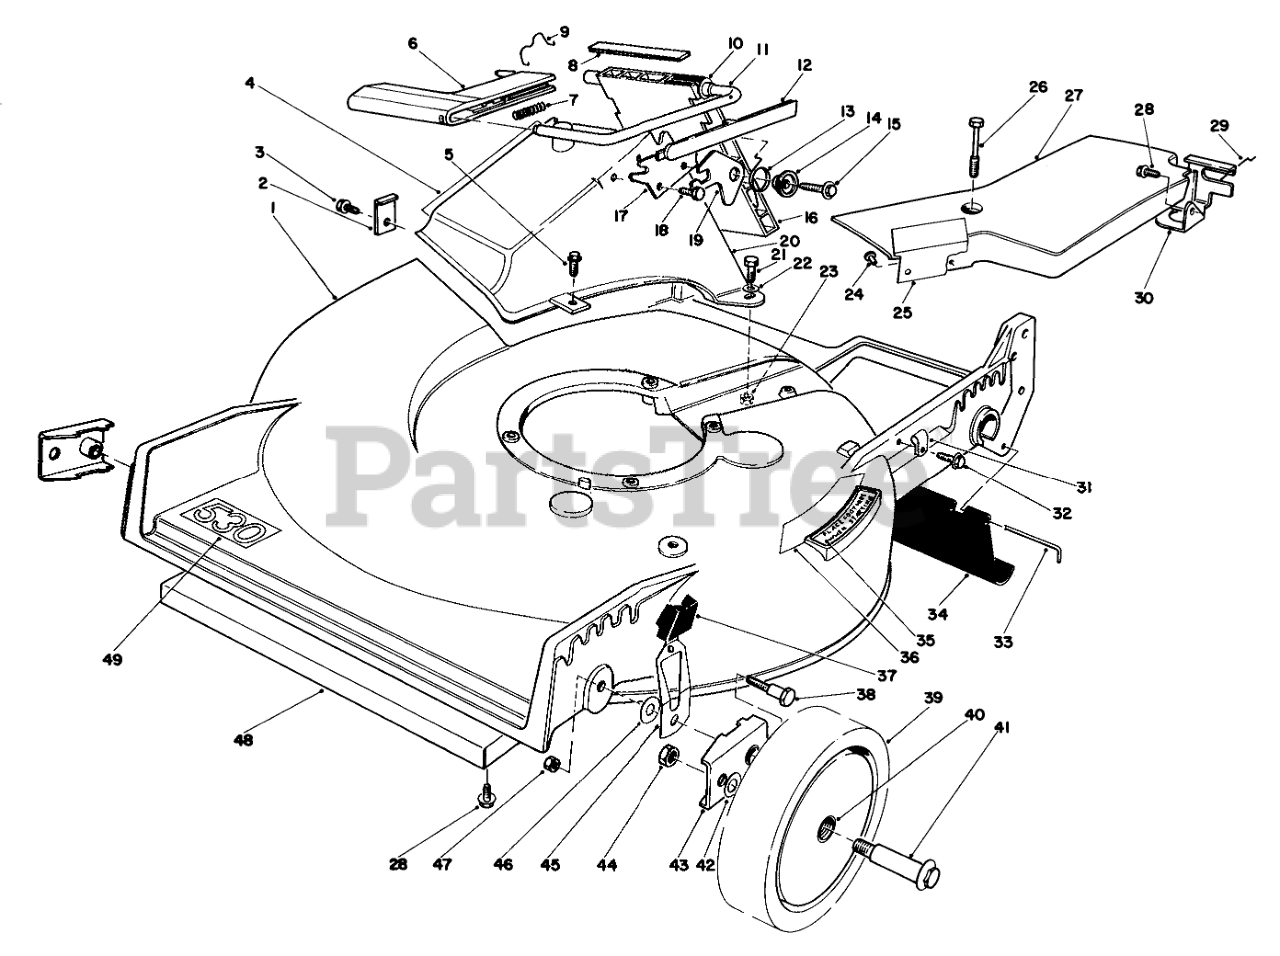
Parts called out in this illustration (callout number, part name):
1	21 SP RB HSG/DECAL
2	TUNNEL CLIP
3	SCREW
4	ATTENTION DECAL
5	Screw
6	Handle-Door
7	Spring
8	DOOR COVER
9	DOOR RET SPRING
10	BUSHING-NYLON
11	DOOR ROD +
12	DOOR HANDLE COVER
13	TORSION SPRING
14	DOOR SPACER
15	SCREW-HWH
16	Door Discharge
17	DOOR LATCH PLATE
18	SCREW-PLASTITE
19	SAFETY LATCH
20	Tunnel Discharge
21	SCREW-HH
22	WASHER-FLAT
23	NUT-LOCK, NI
24	RIVET-HEAD, FLAT
25	HEAT SHIELD
26	SCREW-HHFTF
27	Belt Cover (Incl. Ref. #22 & 29)
28	SCREW-HWHTF
29	RETAINER-CABLE
30	Bracket-Traction Adj.
31	CLAMP-CABLE
32	SCREW
33	ROD-SHIELD
34	SHIELD-TRAILING
35	STEP PAD DECAL
36	Decal-Place Foot Here
37	KNOB-ARM
38	PIVOT SCREW
39	Wheel & Tire Assembly
40	BUSHING
41	BOLT-WHEEL
42	WASHER
43	HP PIVOT ARM ASM
44	Nut
45	Spring Arm
46	WASHER-PIVOT
47	NUT-LOCK, NI
48	Shield-front
49	Decal-530
